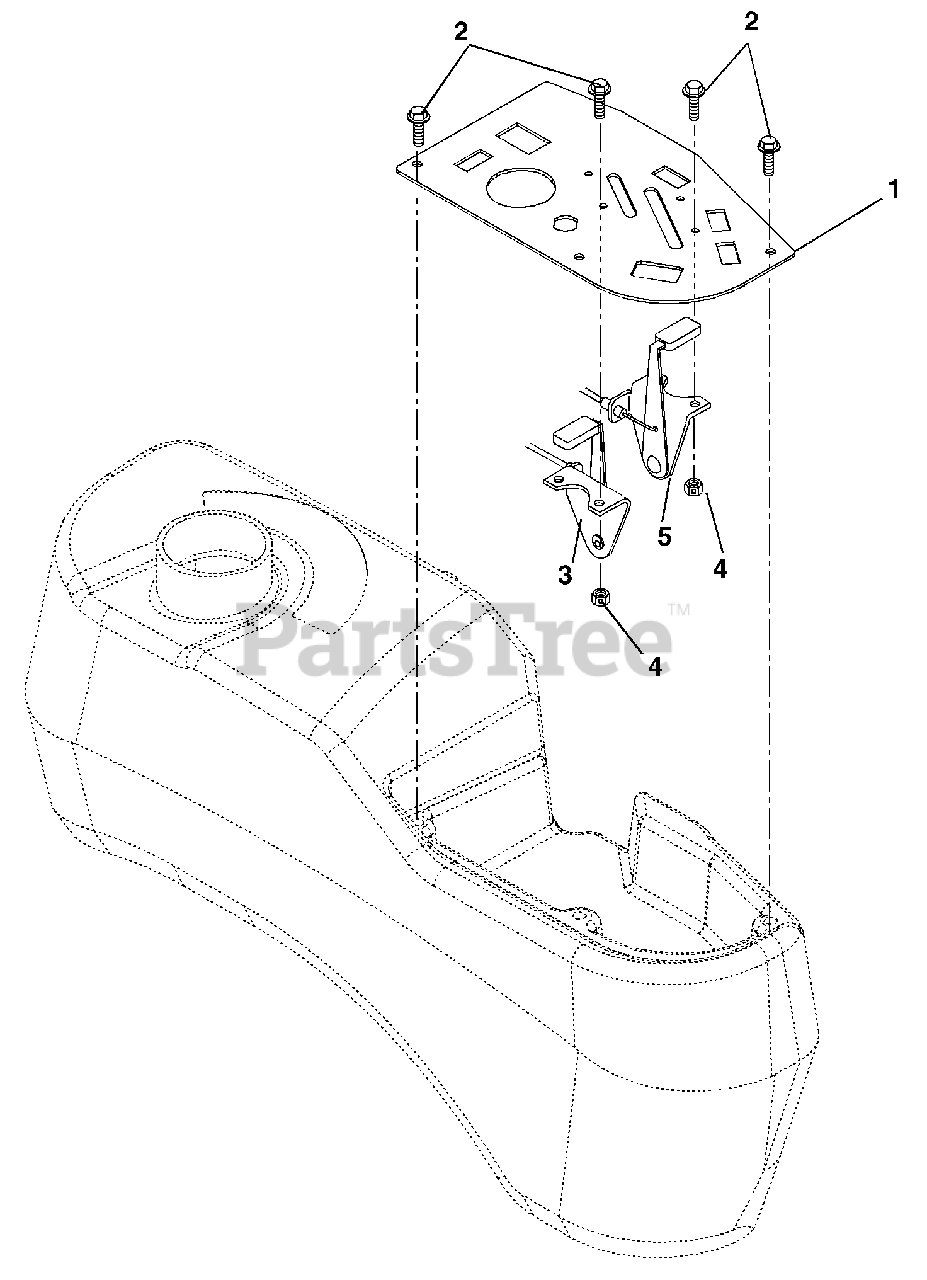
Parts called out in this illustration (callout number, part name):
1	Panel-Control
2	Screw-Machine 10-24 x .50 Hex Washer Head(075, 076, 318, 319)
2	Screw-Machine 10-24 x .50 Hex Washer Head (073, 074)
3	Throttle, Control (075, 076, 318, 319)
3	Throttle, Control (073, 074)
4	Nut-Locking-Nylon 10-24 With Insert(075, 076, 318, 319)
4	Nut-Locking-Nylon 10-24 With Insert (073, 074)
5	Choke Control (073, 074)
